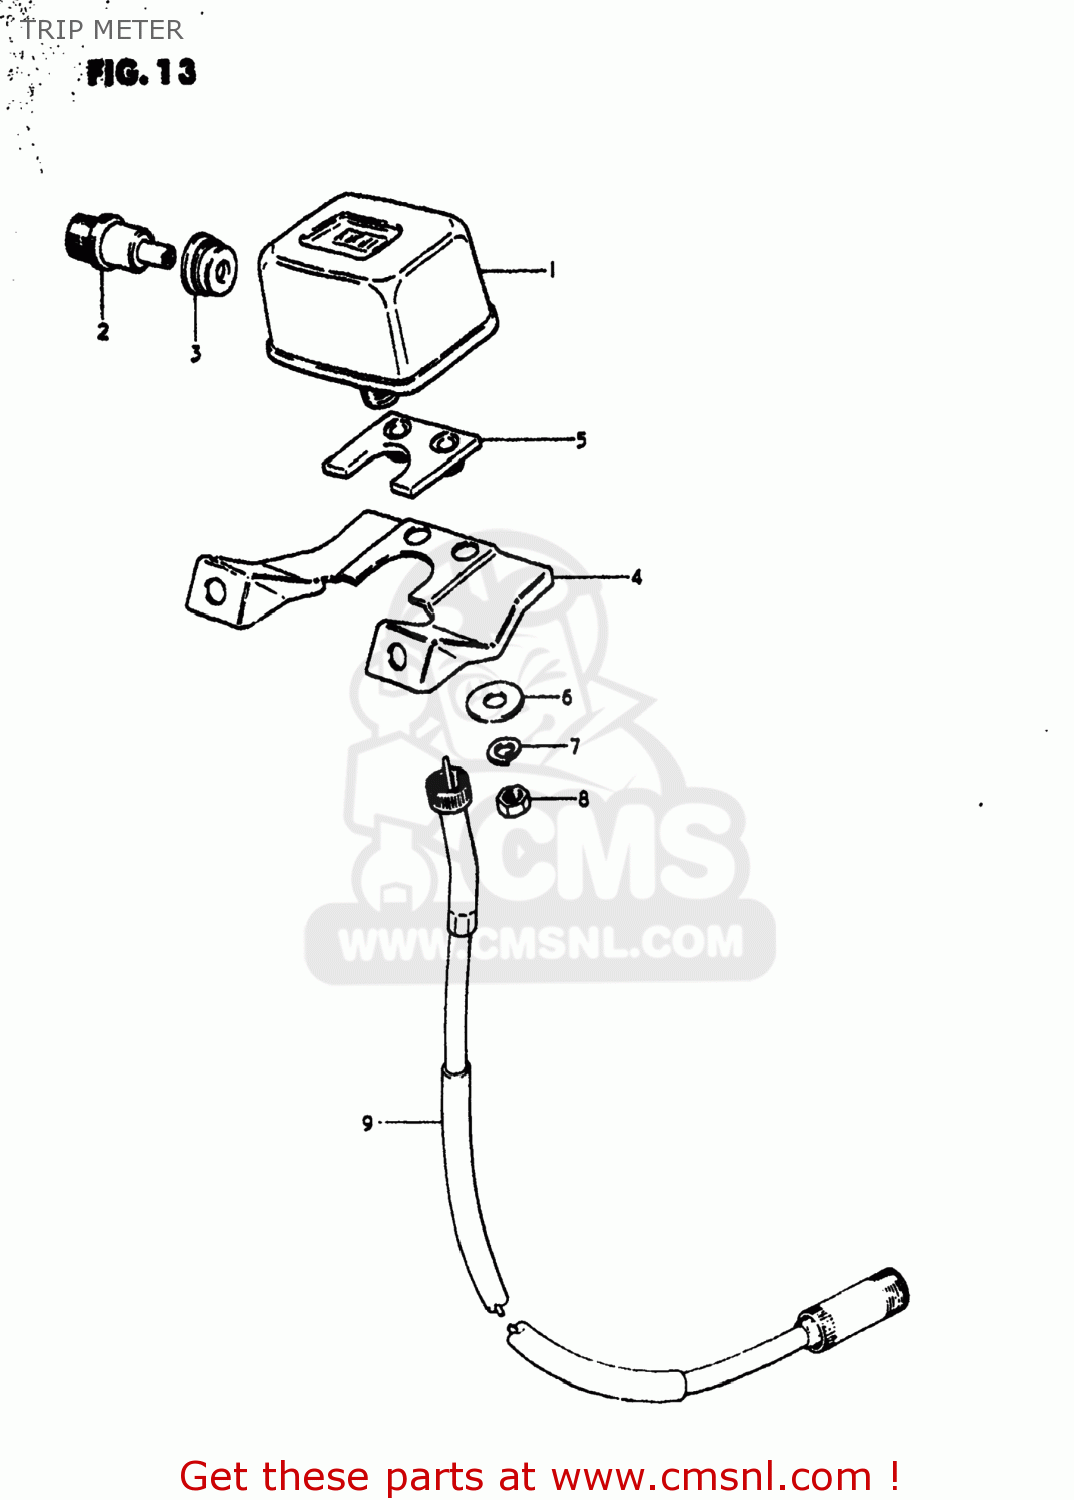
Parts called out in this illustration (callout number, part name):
1	TRIP METER
2	KNOB,TRIP METER
3	COVER,TRIPMETER KNOB
4	BRACKET,TRIPMETER
5	CUSHION,TRIPMETER
6	WASHER,METER
7	LOCK WASHER
8	NUT
9	CABLE ASSEMBLY,SPEEDOMETER
